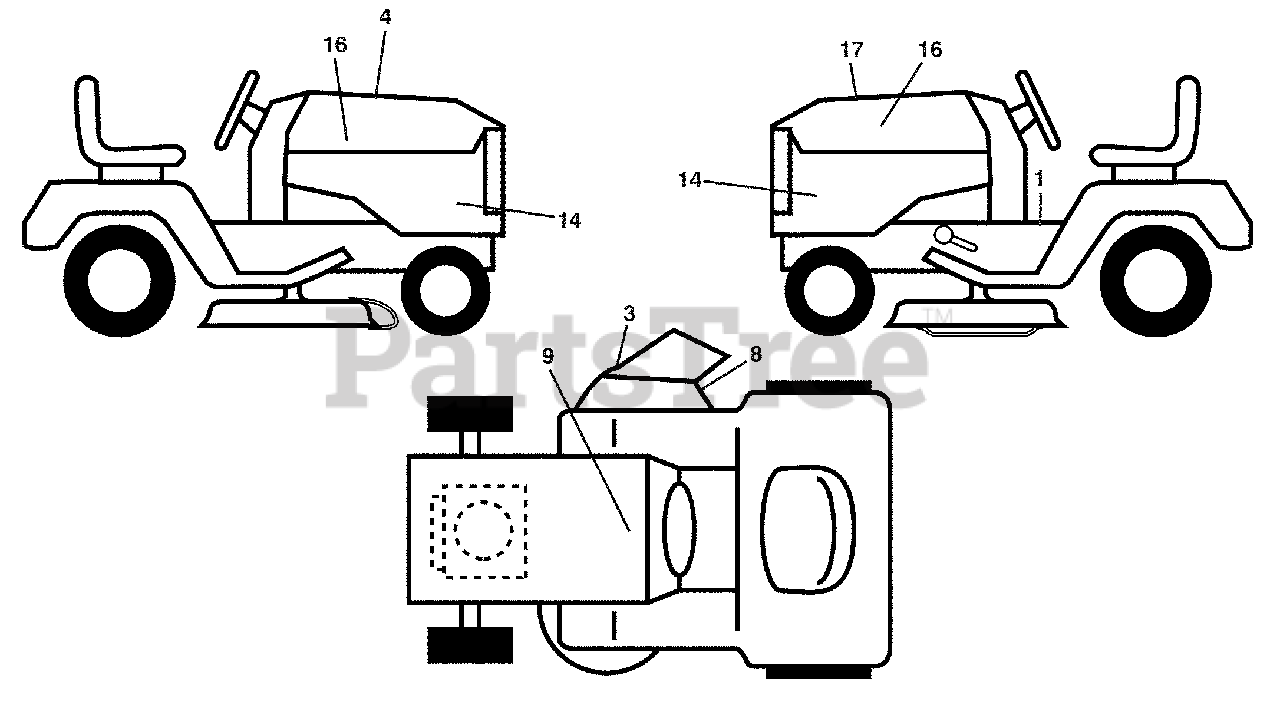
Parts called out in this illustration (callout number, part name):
1	Decal, Fender Warning
3	Decal, Warning
4	Decal, Hood Cust Resp
8	Decal, Mower Sch.
9	Decal, Battery Dnge/Poi
14	Decal, Panel Side
16	Decal, Hood Logo
17	Decal, Replacement
